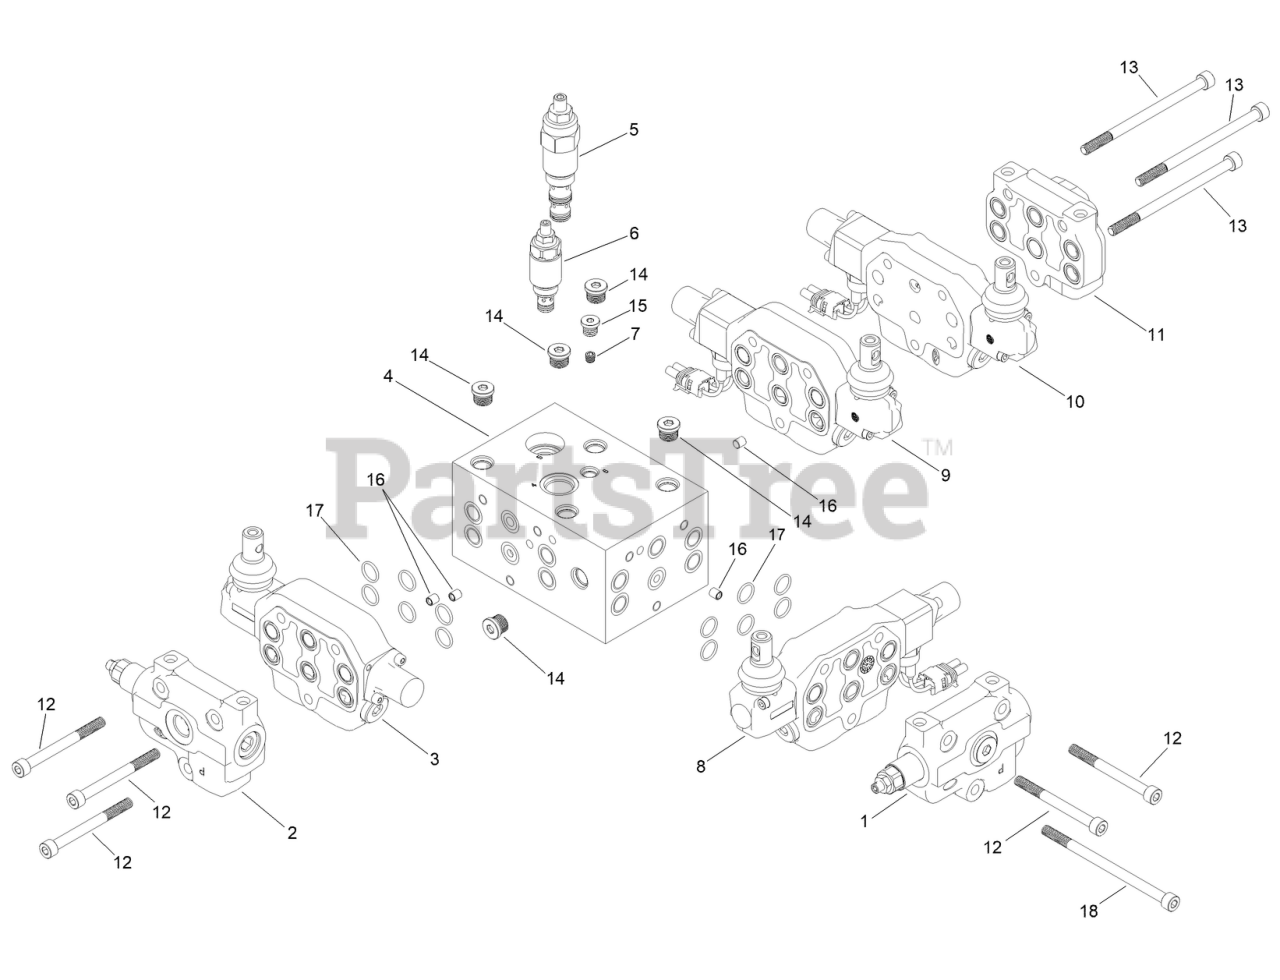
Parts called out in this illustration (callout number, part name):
1	SECTION-INLET
2	SECTION-INLET
3	SECTION-VALVE, SERIES
4	BLOCK-MANIFOLD
5	VALVE-DIRECTIONAL, UNLOADING
6	VALVE-RELIEF
7	PLUG-ORIFICE
8	SECTION-VALVE, PARALLEL
9	SECTION-VALVE, SERIES
10	SECTION-VALVE, PARALLEL
11	SECTION-OUTLET
12	SCREW-HSH
13	SCREW-HSH
16	PLUG-EXPANSION
17	O-RING
18	SCREW-HSH
